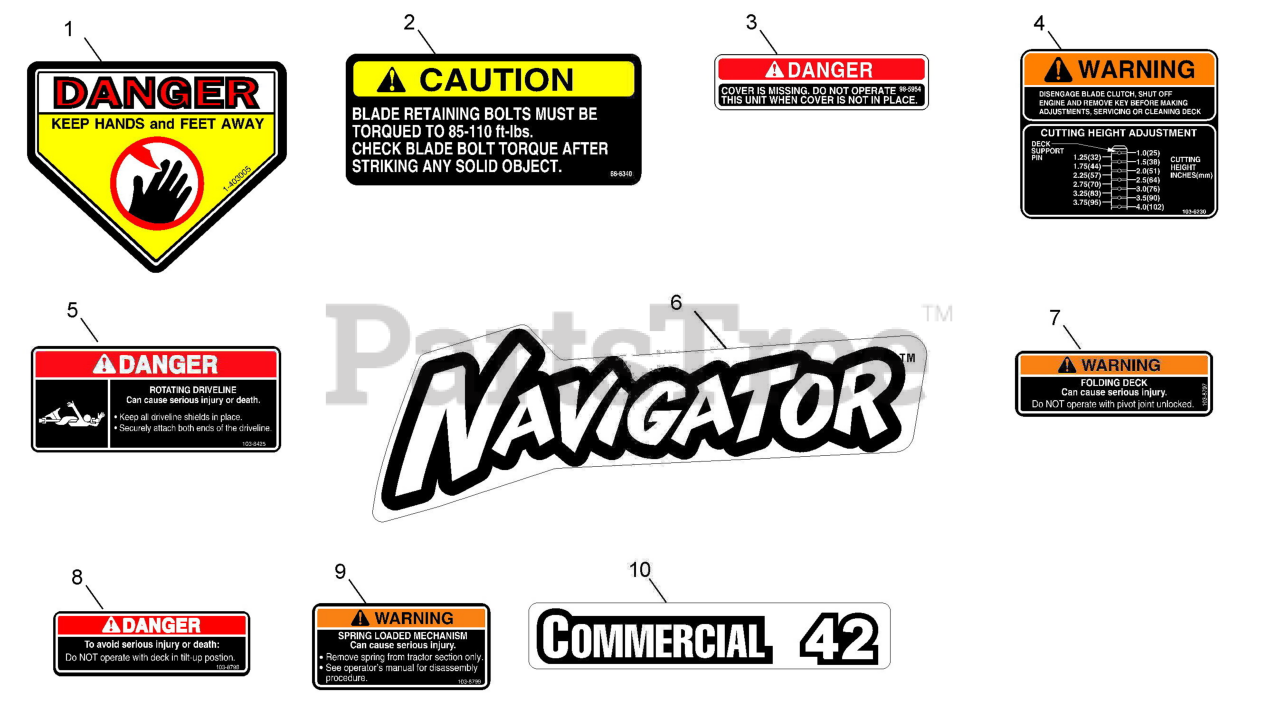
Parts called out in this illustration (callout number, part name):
1	DECAL-DANGER
2	DECAL-TORQUE
3	DECAL-COVER, MISSING
5	DECAL-DRIVELINE
6	DECAL,NAVIGATOR MODEL
7	DECAL-FOLDING DECK
8	DECAL-DANGER
9	DECAL-SPRING
10	DECAL,COMMERCIAL 42
